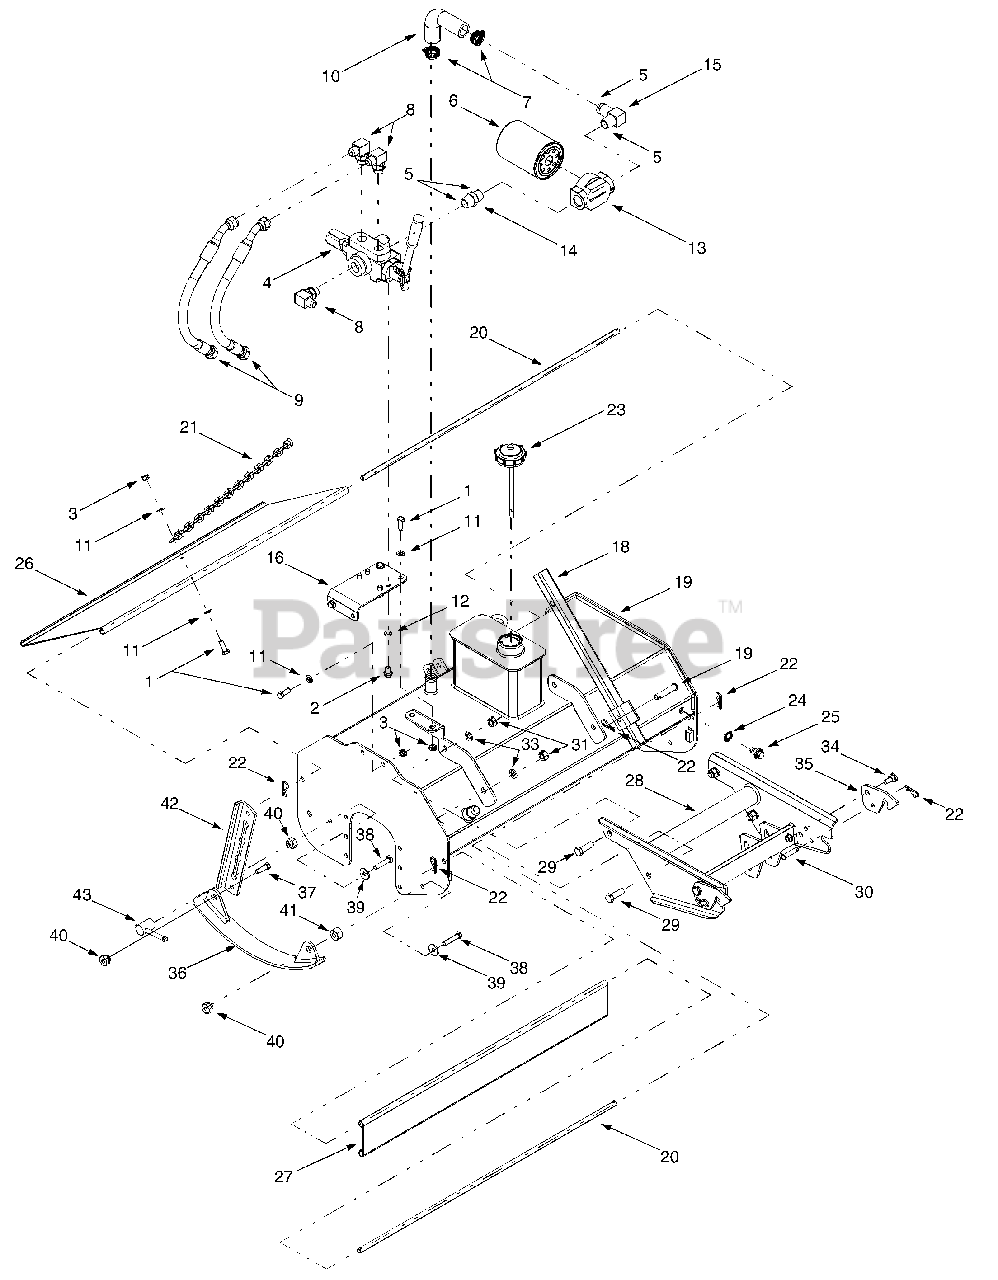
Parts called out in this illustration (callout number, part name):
1	Hex Cap Screw, 3/8-16 x 1.0
2	Shoulder Screw, 3/8-16 x .625
3	Hex Lock Nut, 3/8-16
4	Energy Hydraulic Valve
5	Locktite Hydraulic Sealant
6	Oil Filter
7	Adjustable Hose Clamp
8	90° Hydraulic Adapter, 7/8
9	Hydraulic Hose, 7/8-14
10	90° Hydraulic Hose, 1.37 x 1.0
11	Flat Washer, .375 x .738 x .063
12	Lock Washer, 3/8
13	Filter Housing
14	Hydraulic Adapter, 3/4 x 3/4
15	90° Hydraulic Adapter, 3/4 x 1.0
20	Shield Pivot Rod
21	Chain, 24.37"
22	Internal Cotter Pin
23	Vented Tank Cap
24	Stat-O-Seal O Ring
25	Drain Plug
30	Clevis Pin, 3/8 x 1.75
31	Hex Nut, 1/2-13
33	Lock Washer, 1/2
34	Shoulder Screw, .50 x .27, 3/8-16
38	Hex Cap Screw, 3/8-24 x 1.75
39	Bell Washer, .396 x 1.14 x .095
40	Shoulder Nut, 3/8-24
41	Spacer, 1.0 x .380 x .64
43	Adjuster Crank
